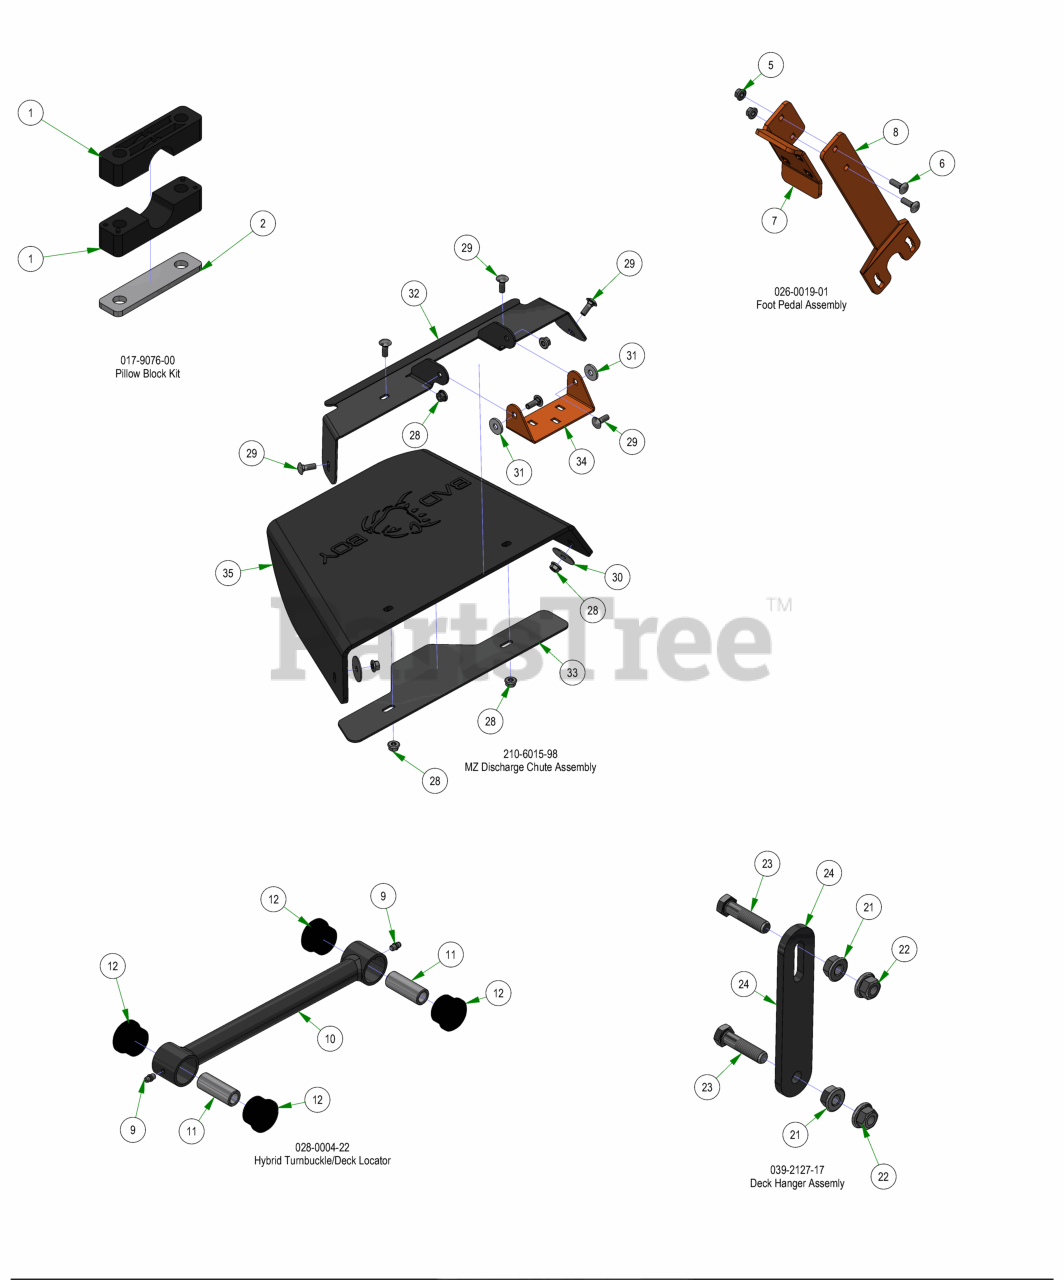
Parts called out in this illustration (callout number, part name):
1	Pillow Block MZ
2	Pillow Block Strap
3	20x10-8 4P A2103 Tire Only
4	8 x 6.375 4H Black Wheel Only
5	5/16-18 NYLON INSERT FLANGE LOCKNUT ZINC
6	5/16-18 X 1 CARRIAGE BOLT (GR.8) ZINC
7	2017 MZ/ZT Shallow Foot Pedal
8	2017 MZ/ZT Deck Pedal Lever
9	1/4-28 Grease Fitting
10	2022 Isolator Turnbuckle Body
11	2018 Maverick Bushing Sleeve
12	2018 Maverick Bushing
13	3/8-24 HEX NUT ZINC YELLOW
14	3/8 FLAT WASHER USS (1" OD) ZINC
15	3/8 SPLIT LOCKWASHER ZINC
16	2017 MZ/ZT Cam Plate
17	2023 Residential Electric Mower Dial Rod
18	Residential E Mower LH Drive Arm
19	2023 Steering Grip
20	Residential E Mower RH Drive Arm
21	3/8-16 HEX SERRATED FLANGE NUT HARD/ZINC
22	3/8-16 NYLON INSERT FLANGE LOCKNUT (GR.F) ZINC
23	3/8-16 X 1-1/2 HEX CAP SCREW (GR.5) ZINC
24	2017 MZ/ZT Deck Hanger
25	Seat Switch
26	SK130 Electric Seat Cover
27	Arm Rest Kit
28	5/16-18 NYLON INSERT FLANGE LOCKNUT ZINC
29	5/16-18 X 7/8 CARRIAGE BOLT ZINC
30	5/16 FENDER WASHER (1-1/2 OD) ZINC
31	.360 ID X .983 OD X .120 THICK FLAT WASHER NYLON
32	Discharge Chute Bracket 48 MZ (Upper)
33	2017 MZ Discharge Chute Bracket-Lower
34	Chute Hanger 48 MZ
35	Rubber Discharge Chute MZ (Component)
36	Pressure Switch
37	Potentiometer
38	Residential E Mower Control Panel
39	Residential E Mower Display
40	Ignition Switch
41	Magnum E-Mower Control Panel Decal
42	Special-use Switch
43	Residential E Mower Floorboard
44	Ratchet Fastener
45	2021 Maverick Floor Mat W/ Reaper Tread
